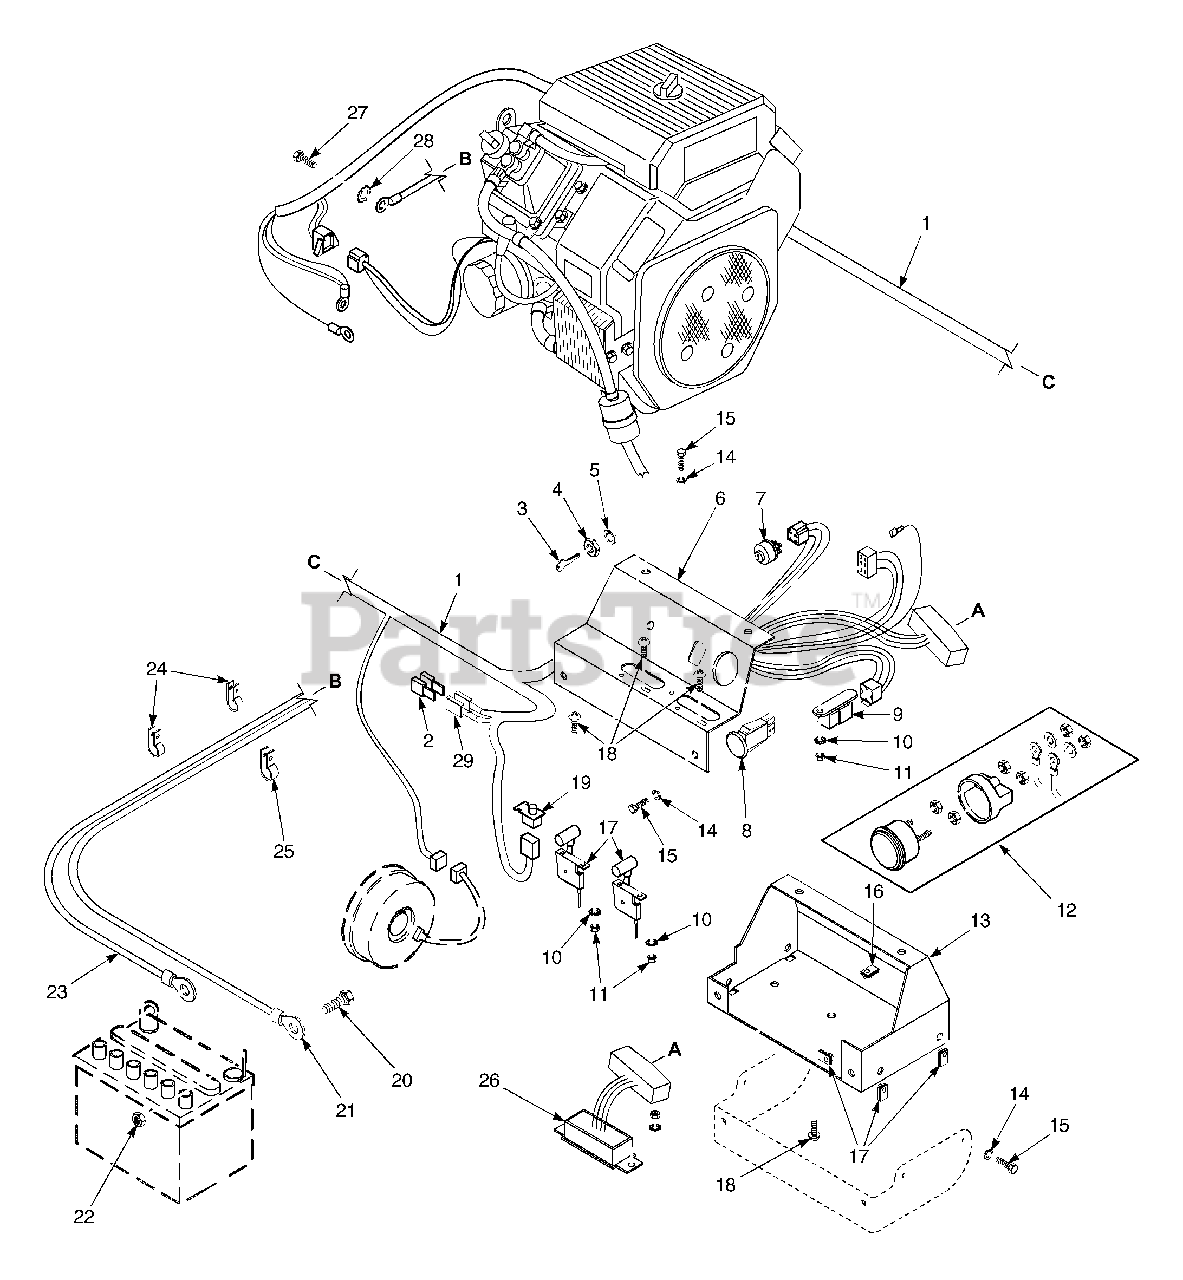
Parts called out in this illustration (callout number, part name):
1	Wire Harness, STT Air Cooled
2	Fuse, 20 AMP
3	Key & Ring Assembly
4	Nut, Hex 5/8-32
5	Lockwasher, 5/8" Internal
6	Instrument Panel, Top w/Decals
7	Key Switch
8	Switch, PTO
9	Relay
10	Lockwasher, #10 External Tooth
11	Nut, Hex #10-32
12	Ammeter
13	Base, Instrument Panel
14	Lockwasher, 1/4"
15	Bolt, Hex Head 1/4-20 x 3/4"
16	U-Nut, 1/4-20
17	Throttle And Choke Controls
18	Screw, Phillips Washer Head #10-32 x 1/2"
19	Switch, Interlock-Seat
20	Bolt, Hex Head 1/4-20 x 1/2"
21	Cable, Battery - Red
22	Nut, Hex 1/4-20
23	Cable, Battery - Black
24	Clamp, Cable 1/2" ID.
25	Clamp, Cable 3/4" ID.
26	Electronic Module
27	Bolt, Hex Head M8-1.25 x 20
28	Lockwasher, 5/16" External Tooth
29	Fuse Holder w/Fuse and Connector
